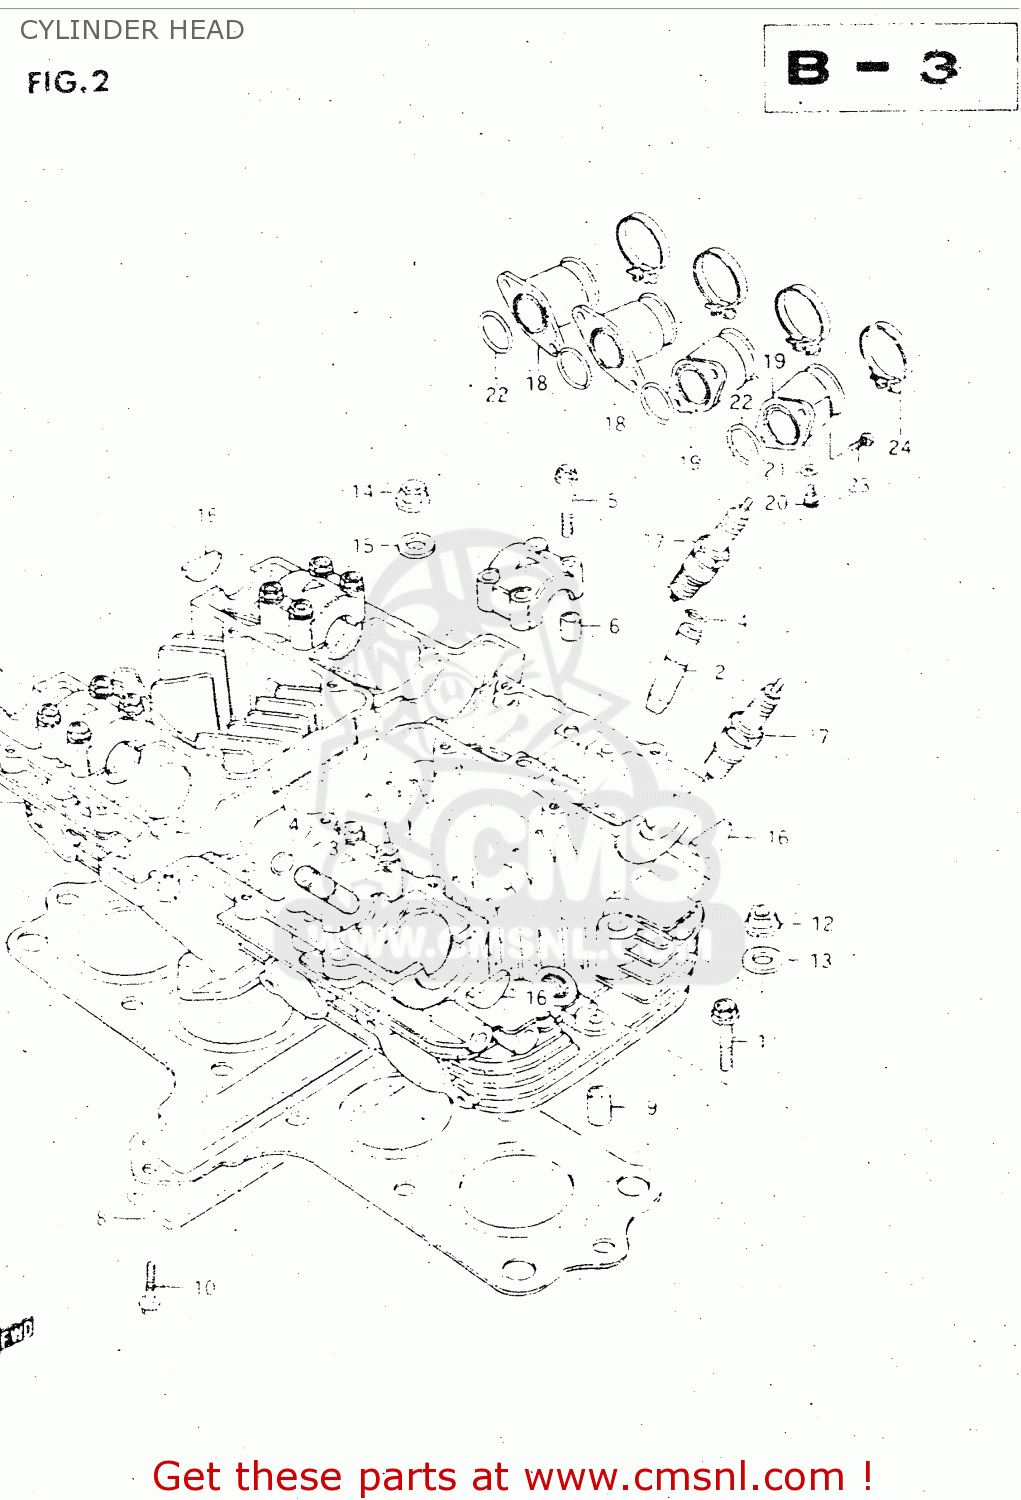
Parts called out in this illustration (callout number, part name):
1	CYLINDER HEAD ASSY
2	GUIDE,INTAKE VALVE
3	GUIDE,EXHAUST VALVE
4	RING,SNAP
5	BOLT(6X39)
6	PIN(6.2X8X11)
7	GASKET
8	O RING(D:3,ID:26X157)
9	PIN
10	BOLT
11	BOLT,UNDER
12	NUT
13	GASKET(8.5X20X2.3) (NAS)
14	NUT
15	WASHER(8.5X19X2.3)
16	PLUG
17	SPARK PLUG DR8ES-L
18	PIPE,INTAKE,R
19	PIPE,INTAKE,L
20	BOLT
21	WASHER
22	O-RING
23	SCREW
24	CLAMP
